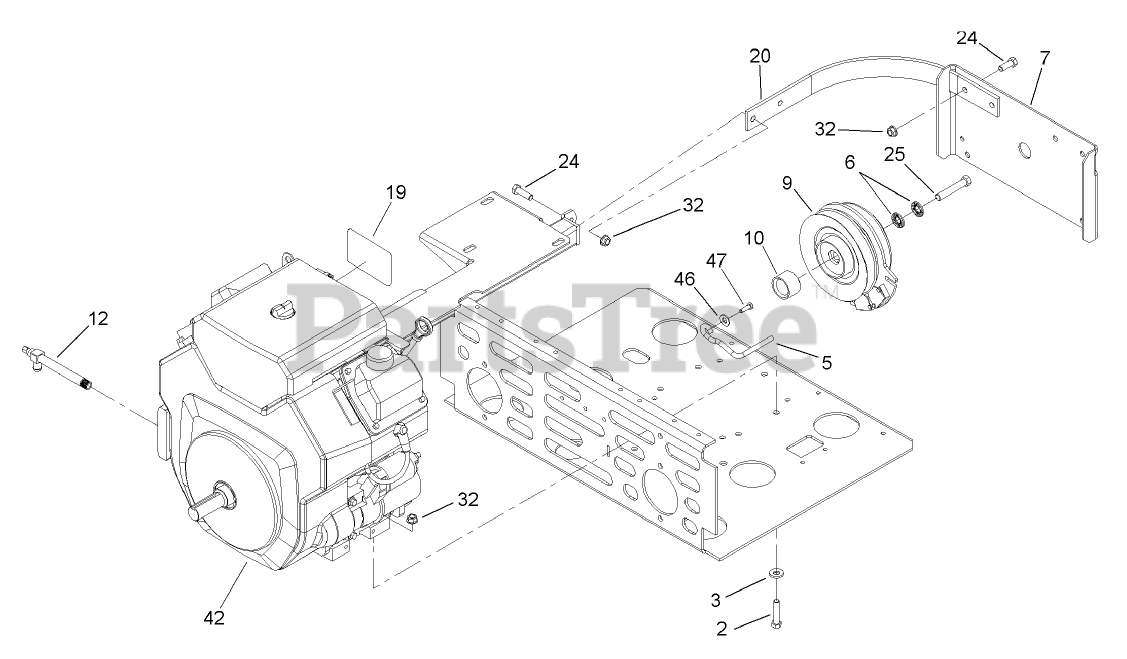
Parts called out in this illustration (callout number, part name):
2	SCREW-HH
3	WASHER-BELLEVILLE
5	ROD-BELT
6	WASHER-SPRING
7	GUARD-CLUTCH
9	Clutch
10	SPACER-CLUTCH
12	VALVE-OIL DRAIN, LONG
20	BRACKET-GUARD, TOP
24	SCREW-HH
25	SCREW-HH
32	NUT-HHF, WHIZ
46	WASHER-FLAT
47	SCREW-HH
